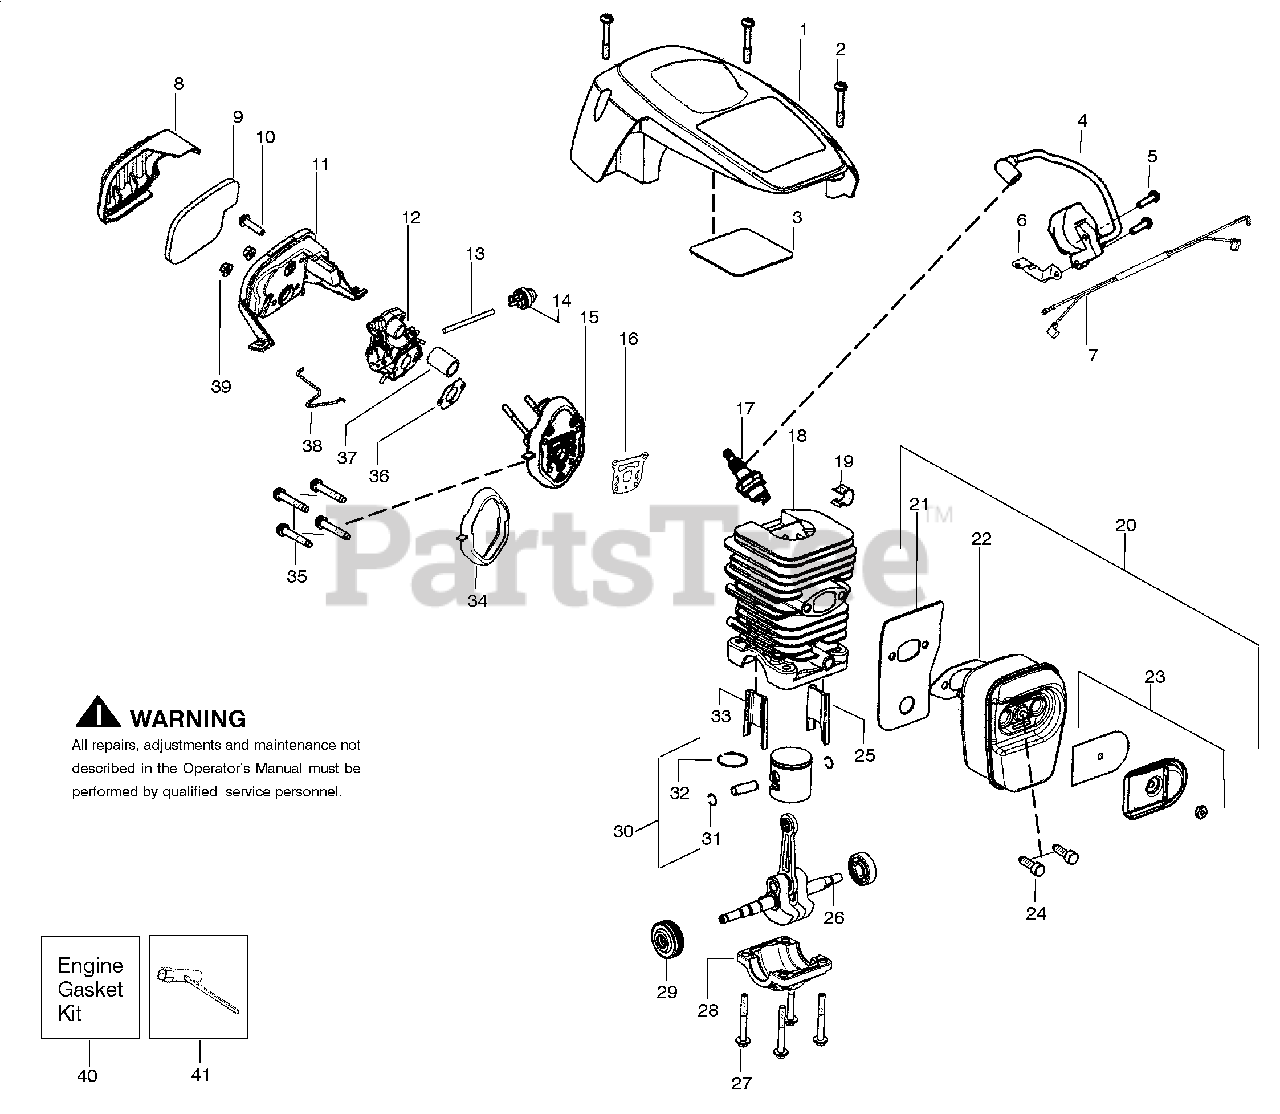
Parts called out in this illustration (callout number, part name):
1	Shield-Cylinder
3	Reflector-Tape
4	Module - Ignition
6	Strap-Ground
7	Assy-Wire Harness
8	Cover-Air Filter
9	Filter-Air
11	Housing-Air Filter
12	Carburetor Zama W-26B
13	Kit-Fuel Line
14	Bulb-Purge "snap-in"
15	Kit-Carb. Adaptor
16	Gasket-cyl. o-ring
17	Accy-Spark Plug
18	Kit-Cylinder
19	Clip-High Tension Lead
20	Kit-Muffler
21	Backplate-Muffler
22	Gasket-Muffler
23	Kit-Spark Arrestor
24	Bolt-Muffler
25	Insert-Left Cyl.
26	Assy-Crankshaft/Rod
28	Cap-Crankcase
29	Assy-Bearing/Seal
30	Kit-Piston
31	Retainer-Piston Pin
32	Ring-Piston
33	Insert-Right Cyl.
34	Seal-Adaptor
36	Gasket-Carb.
37	Tube-Intake
38	Wire-Throttle
39	Nut-Carb.
40	Kit-Gasket
41	Wrench-Bar
